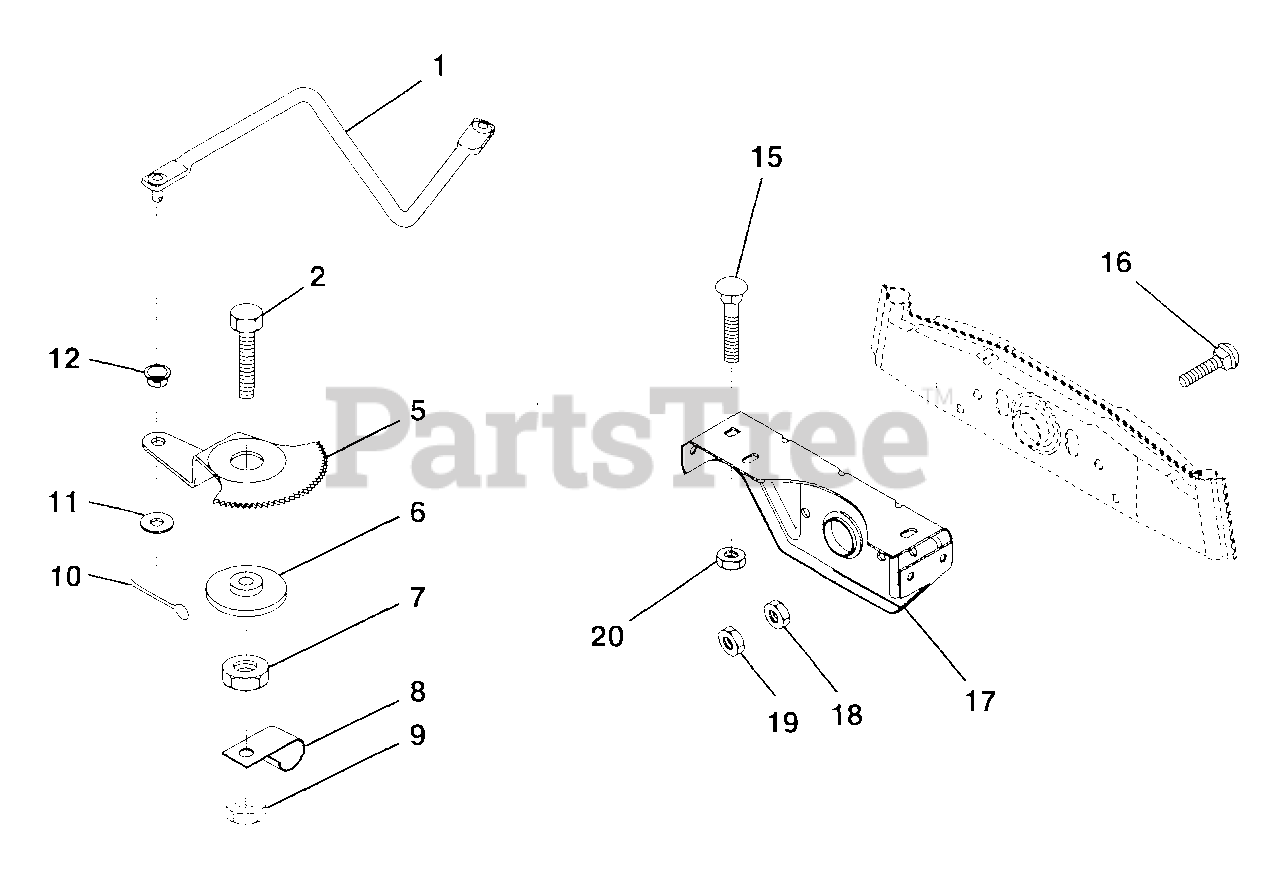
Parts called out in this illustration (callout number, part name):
1	Link, Drag
2	Bolt, Hex, Fin. 1/2-13 x 1-3/4
5	Gear, Sector
7	Nut, Heavy Hex, Top Lock 1/2-13 UNC
8	Clip, Insulated
9	Nut, Crown lock 3/8-16
10	Pin, Cotter 1/8 x 3/4
11	Washer 13/32 x 13/16 x 16 Ga.
15	Bolt, Carriage 3/8-16 UNC x 3/4
16	Bolt, Carriage
17	Support, Front Axle
18	Nut, Hex, Fin. 3/8-16 UNC
19	Nut, Centerlock 3/8-16 UNC
20	Nut, Crown lock 3/8-16 UNC
